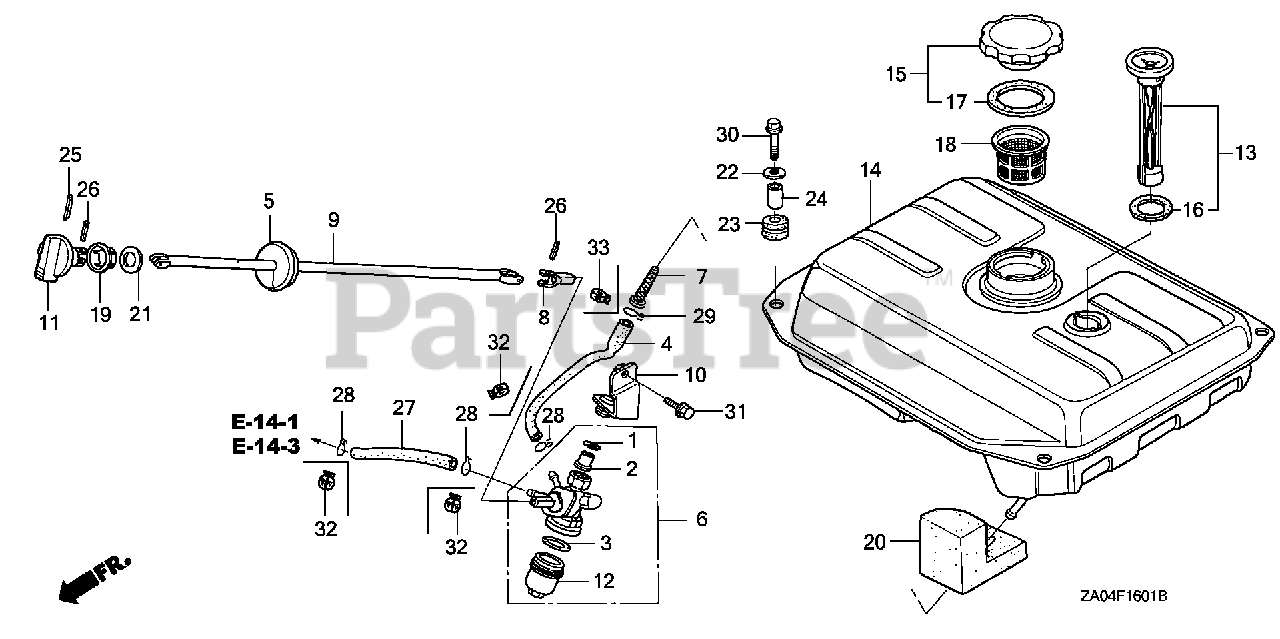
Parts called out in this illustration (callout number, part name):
3	GASKET, FUEL STRAINER CUP
4	TUBE, FUEL TANK
4	TUBE, FUEL TANK (FKM)
6	PETCOCK ASSY., FUEL
7	FILTER, FUEL
8	JOINT, PETCOCK CONTROL
9	SHAFT, PETCOCK CONTROL
10	STAY, PETCOCK
11	KNOB, PETCOCK CONTROL
12	CUP, FUEL STRAINER
13	METER, FUEL
14	TANK, FUEL *NH105* (MAT BLACK)
15	CAP, FUEL FILLER
16	GASKET C, FUEL METER
17	GASKET, FUEL FILLER CAP
18	FILTER, FUEL
19	BUSH, PETCOCK SHAFT
20	RUBBER A, SEPARATOR SEAL
21	WASHER, THRUST (18.6MM)
22	WASHER, TANK CUSHION
23	CUSHION, TANK RUBBER
24	COLLAR, TANK CUSHION
25	PIN, COTTER (2.0X35)
26	PIN, SPRING (2.5X16)
27	BULK HOSE, FUEL (4.5X3000) (Honda Code 5137104). (4.5X140)
27	TUBE, FUEL (4.5X75) (FKM)
28	CLIP, TUBE (B8)
29	CLIP, TUBE (B10)
30	BOLT, FLANGE (6X22)
31	BOLT, FLANGE (6X12) Use up to Engine SN 1543277.
32	CLIP, TUBE (D8)
33	CLIP, TUBE (10.5MM)
